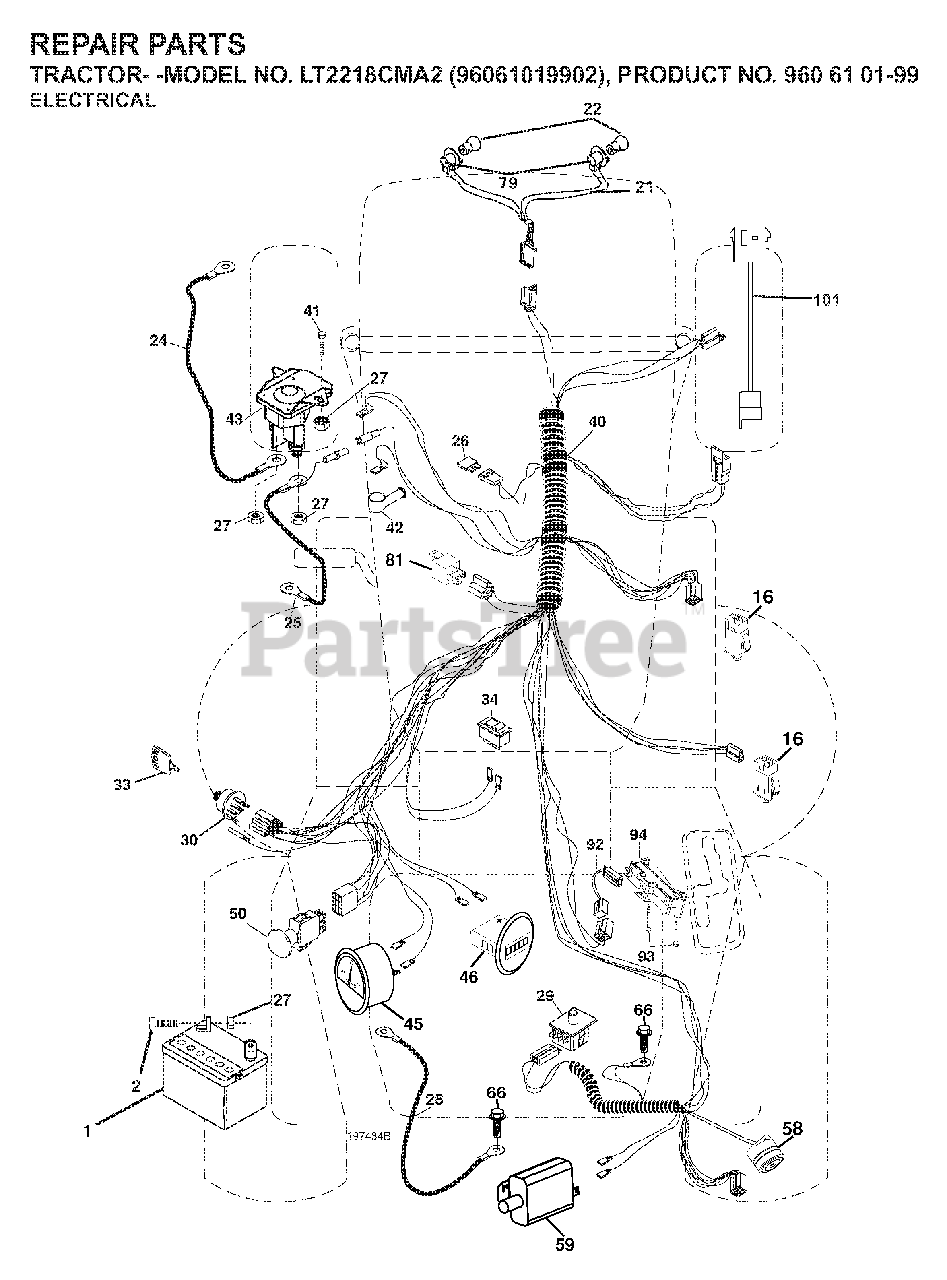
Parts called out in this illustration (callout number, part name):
1	BATTERY 12V .35 AMP
16	SWITCH INTERLOOK PUSH-IN
21	HARNESS.W/LIGHT SOCKET
22	LIGHTBULB
24	BATTERY CABLE GT
25	CABLE BATTERY
26	FUSE 20AMP
27	NUT
28	CABLE GROUND
29	SWITCH.SEAT.DP W/RAMPS
30	SWITCH.IGN.DELTA.W.LGH.ROS
33	KEY MLD GEN DELTA
34	SWITCH LT
42	TERMINAL COVER
43	SOLENOID.W/BRASS.PLUNG
46	HOURMETER SNAP-IN
50	PTO SWITCH
58	BUZZER
79	BULB HOLDER ASM.
81	RELAY.ASSY.T
92	HARNESS.PIGTAIL.CONSLE
93	SCREW.PLASTITE
94	MODULE.REVERSE.ROS
101	PIGTAIL.MATNLK.NEW.HAR
